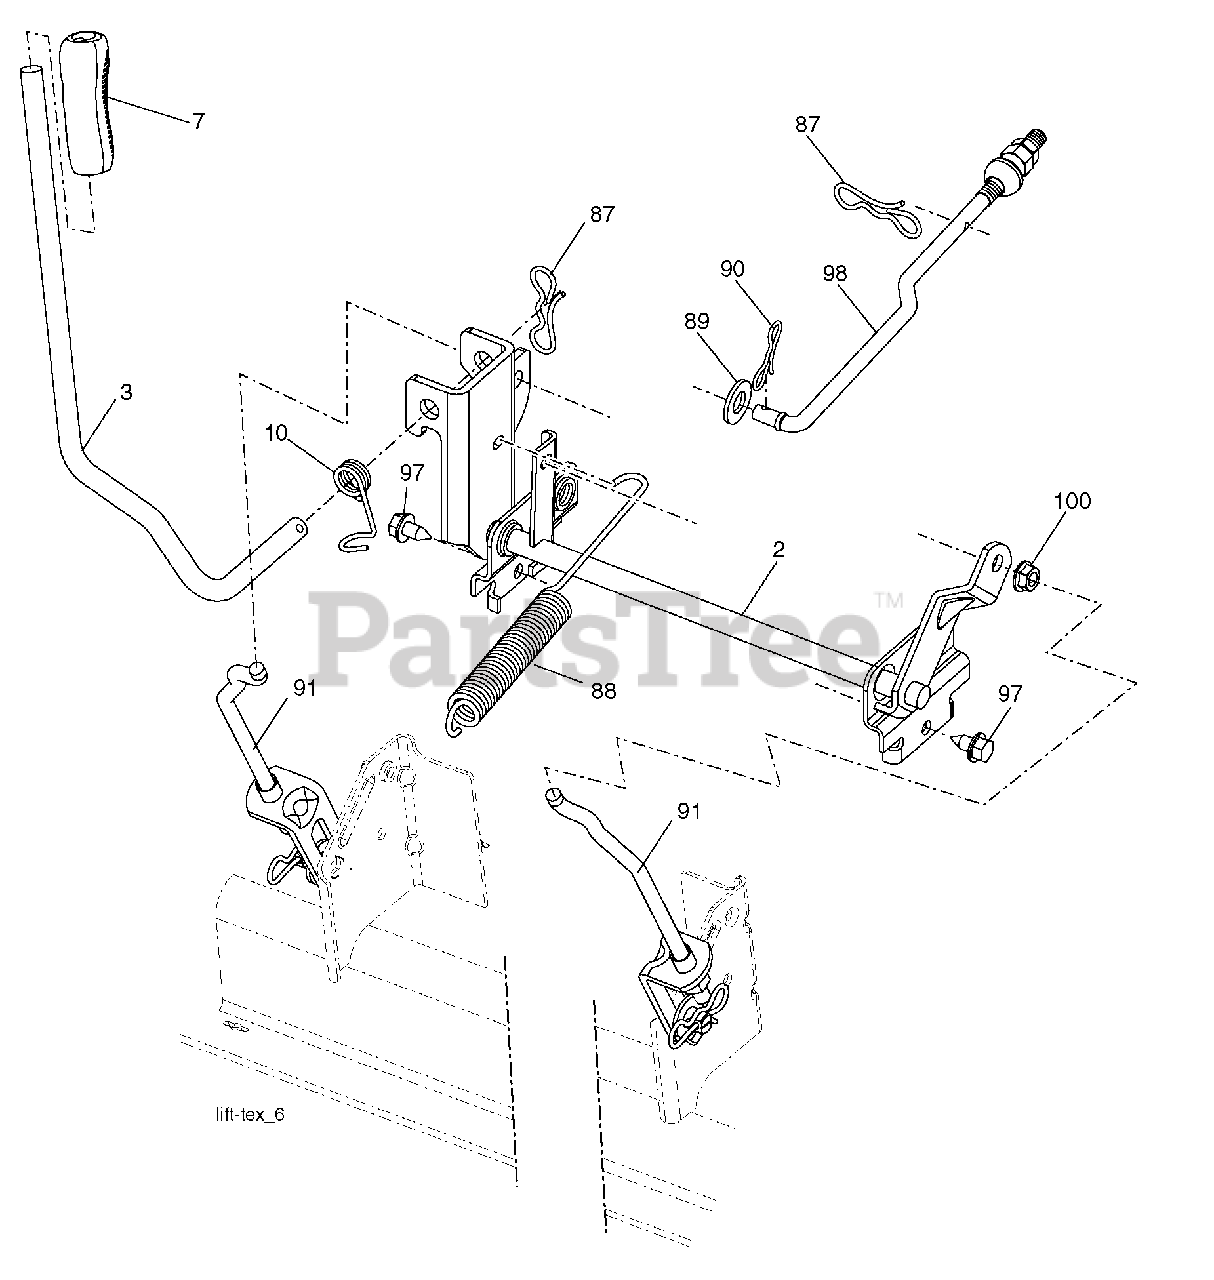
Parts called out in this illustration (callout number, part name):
2	Shaft Asm., Lift
3	Lever Asm., Lift RH
7	Grip, Lever
10	Spring Torsion
87	Pin Cotter 7/16 Bow Tie Lock
88	Spring Lift Assist
89	Washer Clear Zinc
90	Pin Cotter 5/16 Bow Tie Lock
91	Link Lift Susp. Mower Rear
97	Screw 3/8-16 x .75 R.Z
98	Link Lift Susp. Front Mower
100	Nut Centerlock 3/8-16 unc
